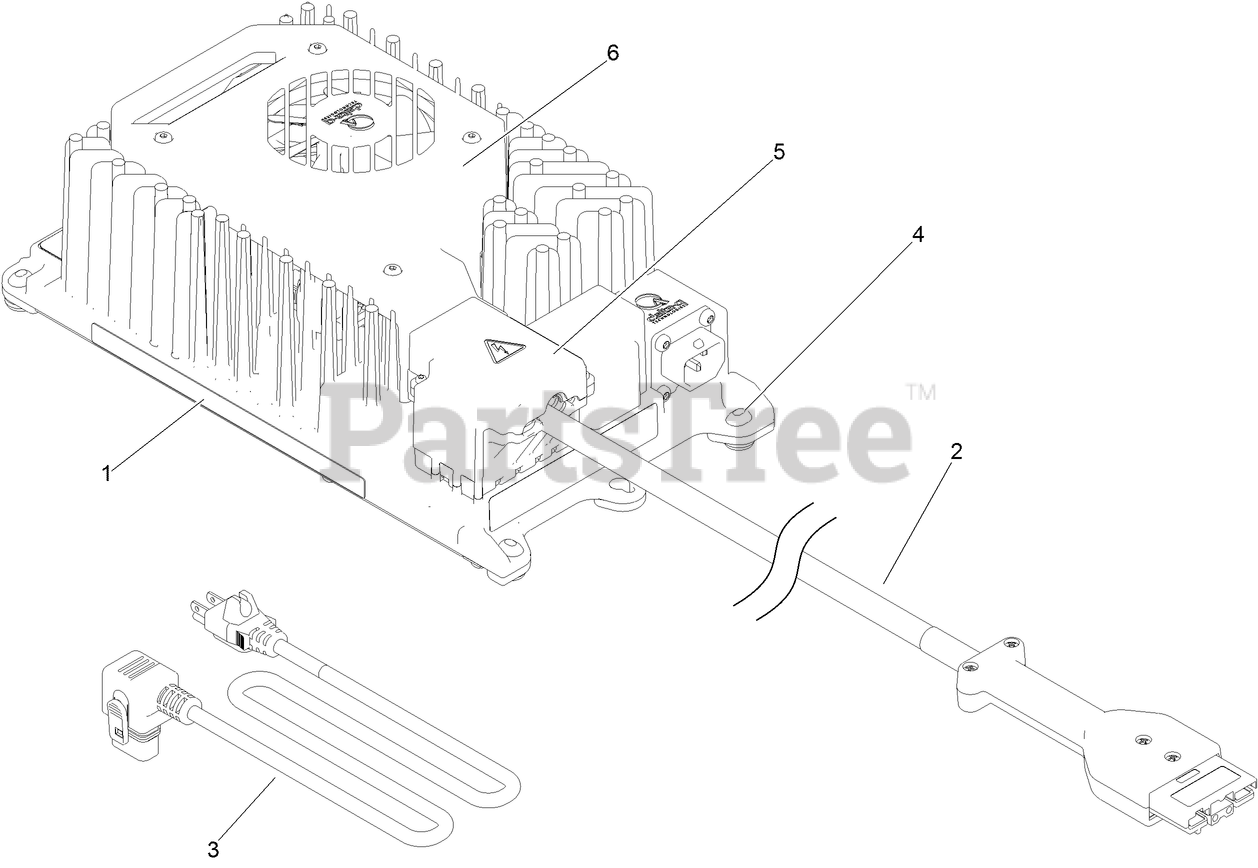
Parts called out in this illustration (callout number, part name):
1	DECAL-CHARGER
2	CORD-DC W/CAN BUS
3	CORD-AC, 120V
4	HANDLE AND FEET KIT
5	COVER-PLASTIC, DC POWER
6	FAN-SERVICE
